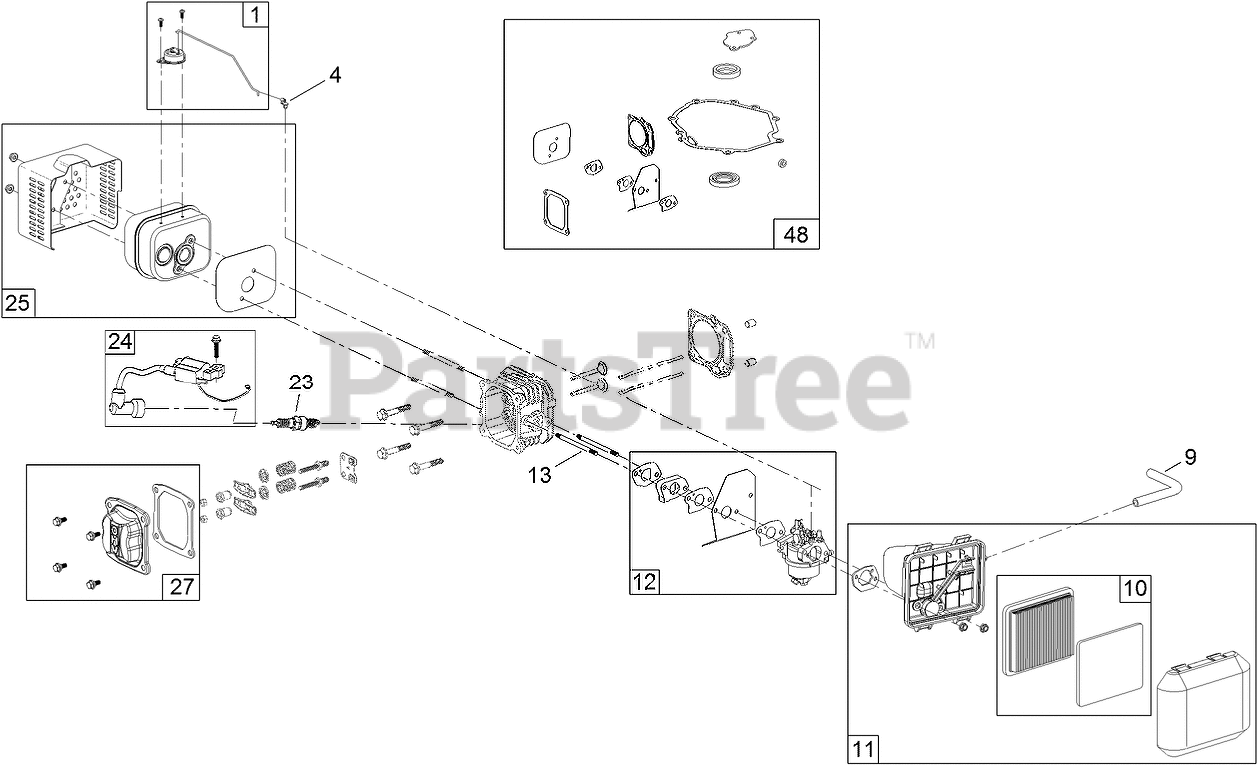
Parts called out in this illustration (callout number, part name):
1	THERMAL CHOKE CONTROL KIT
4	LOCK-THROTTLE
9	TUBE-BREATHER
10	AIR FILTER AND PREFILTER KIT
11	AIR CLEANER ASM
12	CARBURETOR REPAIR KIT
12	CARBURETOR COMPLETE KIT
13	STUD-INTAKE
23	SPARK PLUG
24	IGNITION AND HARDWARE KIT
25	MUFFLER AND SHIELD KIT
27	VALVE COVER KIT
48	SEAL AND GASKET KIT
